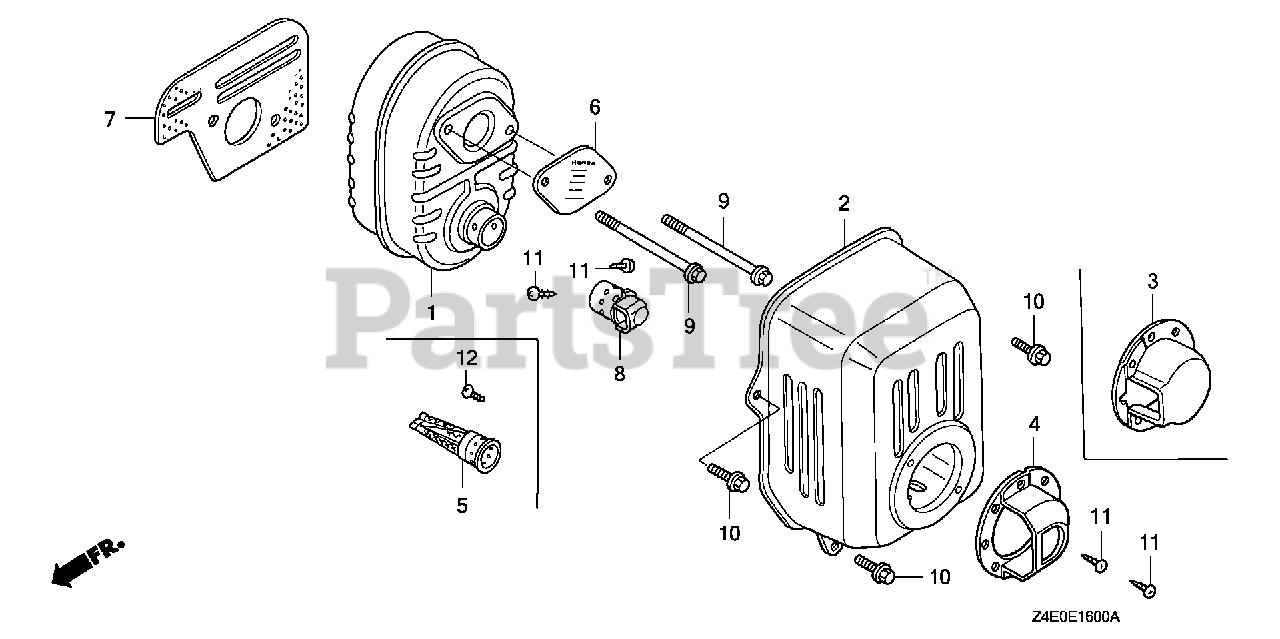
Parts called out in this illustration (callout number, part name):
1	MUFFLER
2	PROTECTOR, MUFFLER
4	CAP, MUFFLER (TO 1207644)
5	ARRESTER, SPARK (TO 1207644)
7	GASKET, MUFFLER
8	DEFLECTOR, MUFFLER (TO 1207644)
9	BOLT, FLANGE (6X79) (CT200)
10	BOLT, FLANGE (6X14)
11	SCREW, TAPPING (4X6) (TO INSTALL OPTIONAL SPARK ARRESTER)
12	SCREW, TAPPING (4X6) (TO INSTALL OPTIONAL SPARK ARRESTER)
